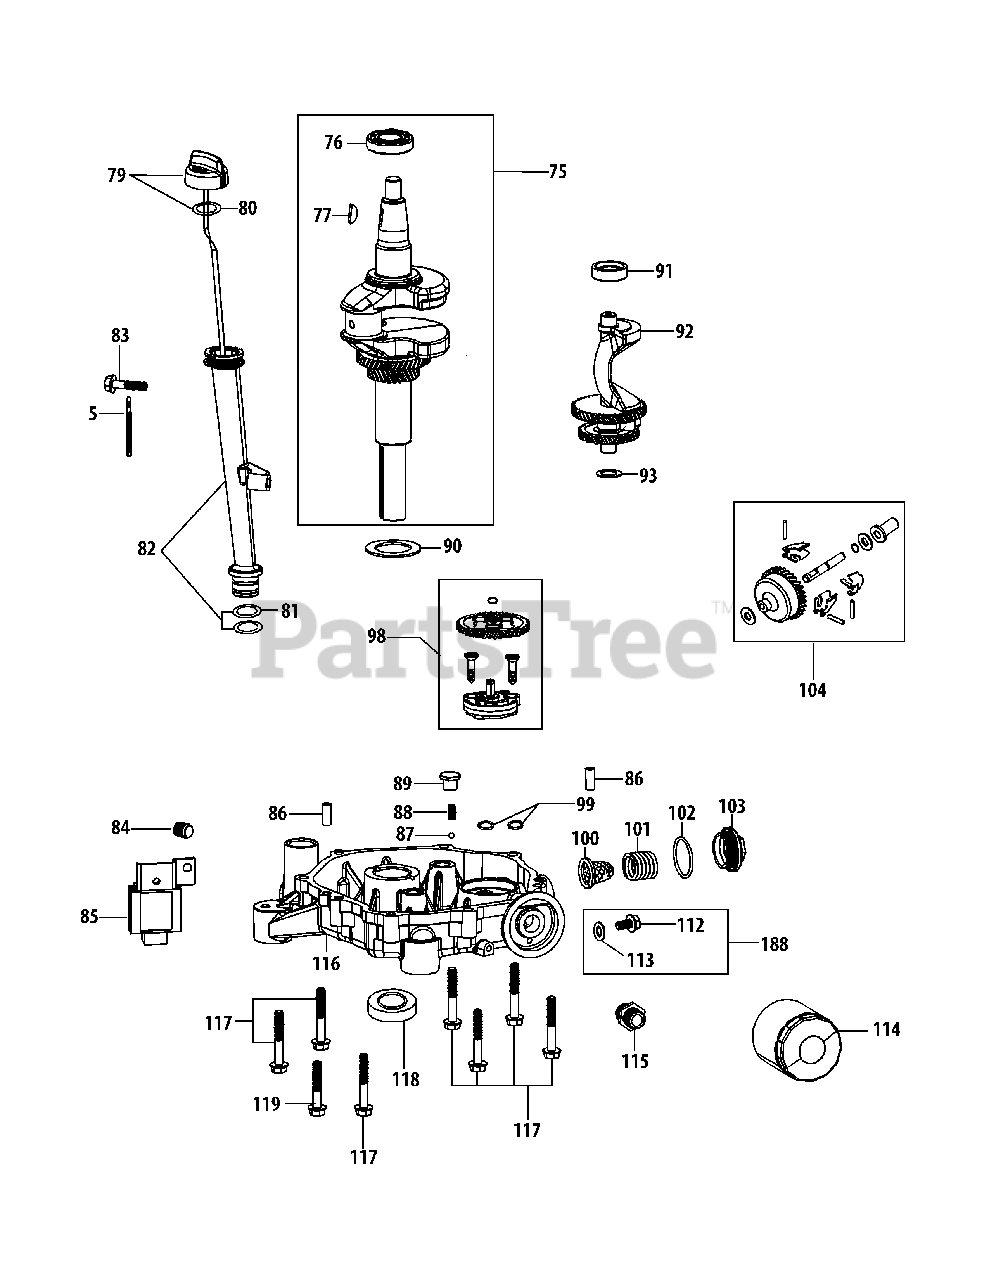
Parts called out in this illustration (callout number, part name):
5	FLEXIBLE CLAMP
75	Crankshaft Assembly
76	Main Bearing
77	Woodruff Key
79	Dipstick Assembly
80	Upper O-Ring
81	Lower O-Ring
82	Oil Fill Tube Assembly
83	Bolt M6x35
84	ENGINE PLUG 3/8 NPT
85	Regulator
86	Dowel Pin 8x14
87	Ball 6.35
88	Spring
90	Crankshaft Thrust Washer
91	Balanceable Shaft Bearing
92	Balanceable Shaft Assembly
93	Balanceable Thrust Washer
98	Oil Pump Assembly
99	O-Ring 10x2.65
100	Filter
101	Filter Spring
102	O-Ring 35.5x2.65
103	Filter Cover
104	Governor Gear/Shaft Assembly
112	Bolt M8x15
113	Oil Drain Plug Washer
114	Oil Filter
115	Screw Joint
116	Crankcase Cover
116	Crankcase Cover Assembly
117	Bolt M8x54
118	Lower Crankshaft Seal
119	Bolt M8x43
188	Oil Drain Plug Assembly
